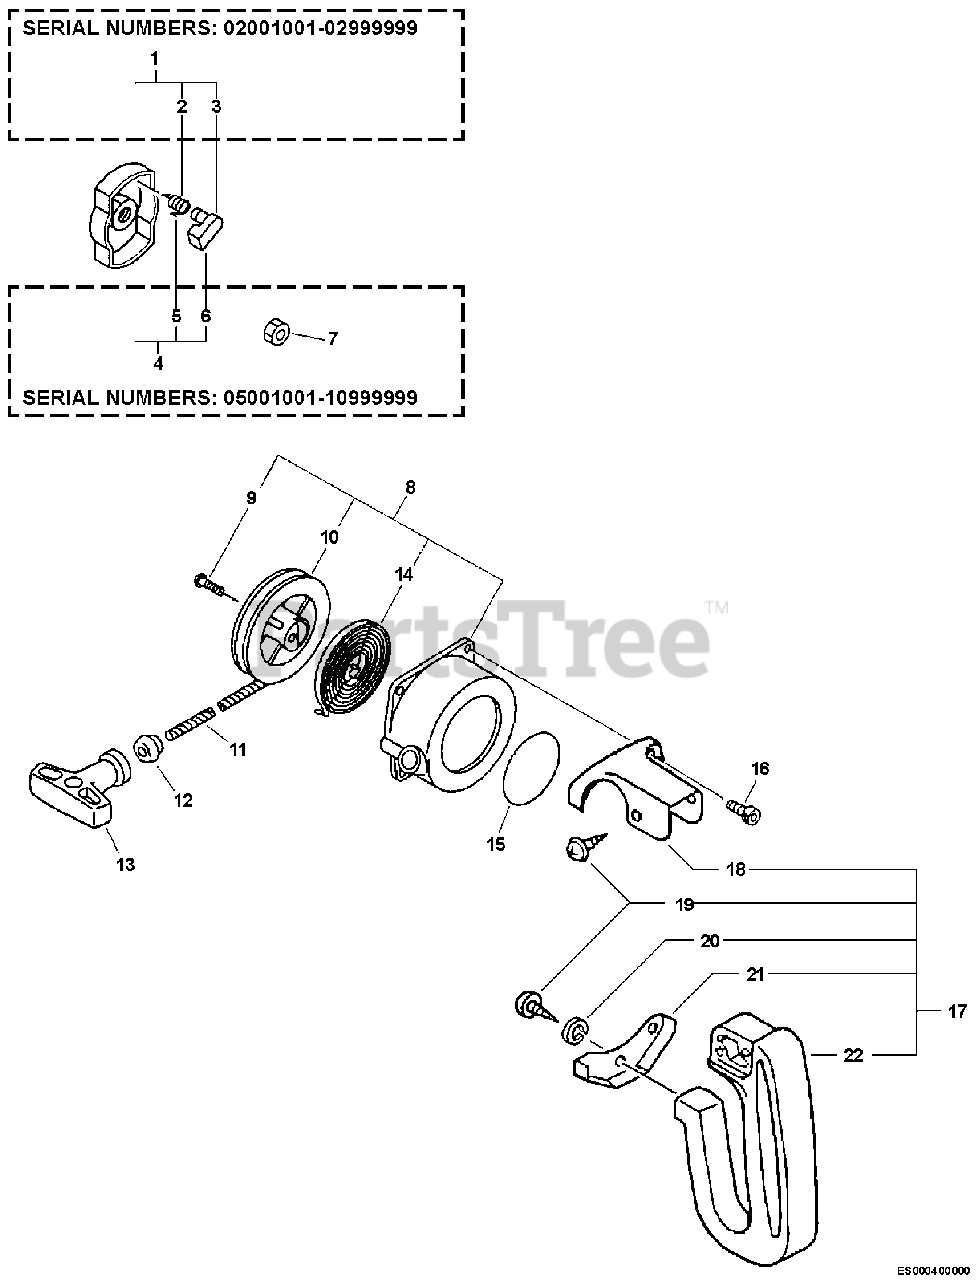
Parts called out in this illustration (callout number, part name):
1	PAWL ASSY, STARTER
2	SPRING, RETURN
3	PAWL, STARTER - BLACK
4	PAWL ASSY, STARTER
5	SPRING, RETURN
6	PAWL, STARTER - BLACK
8	STARTER ASSY, RECOIL
9	SCREW
10	REEL, ROPE
11	ROPE, STARTER 3.0×1000
12	GUIDE, ROPE
13	GRIP, STARTER
14	SPRING, RECOIL
15	LABEL, ECHO
16	BOLT 4×16
17	HANDLE ASSY, SIDE
18	BRACKET, UPPER HANDLE
19	SCREW 5×16
20	WASHER, SPRING 5
21	BRACKET, LOWER HANDLE
